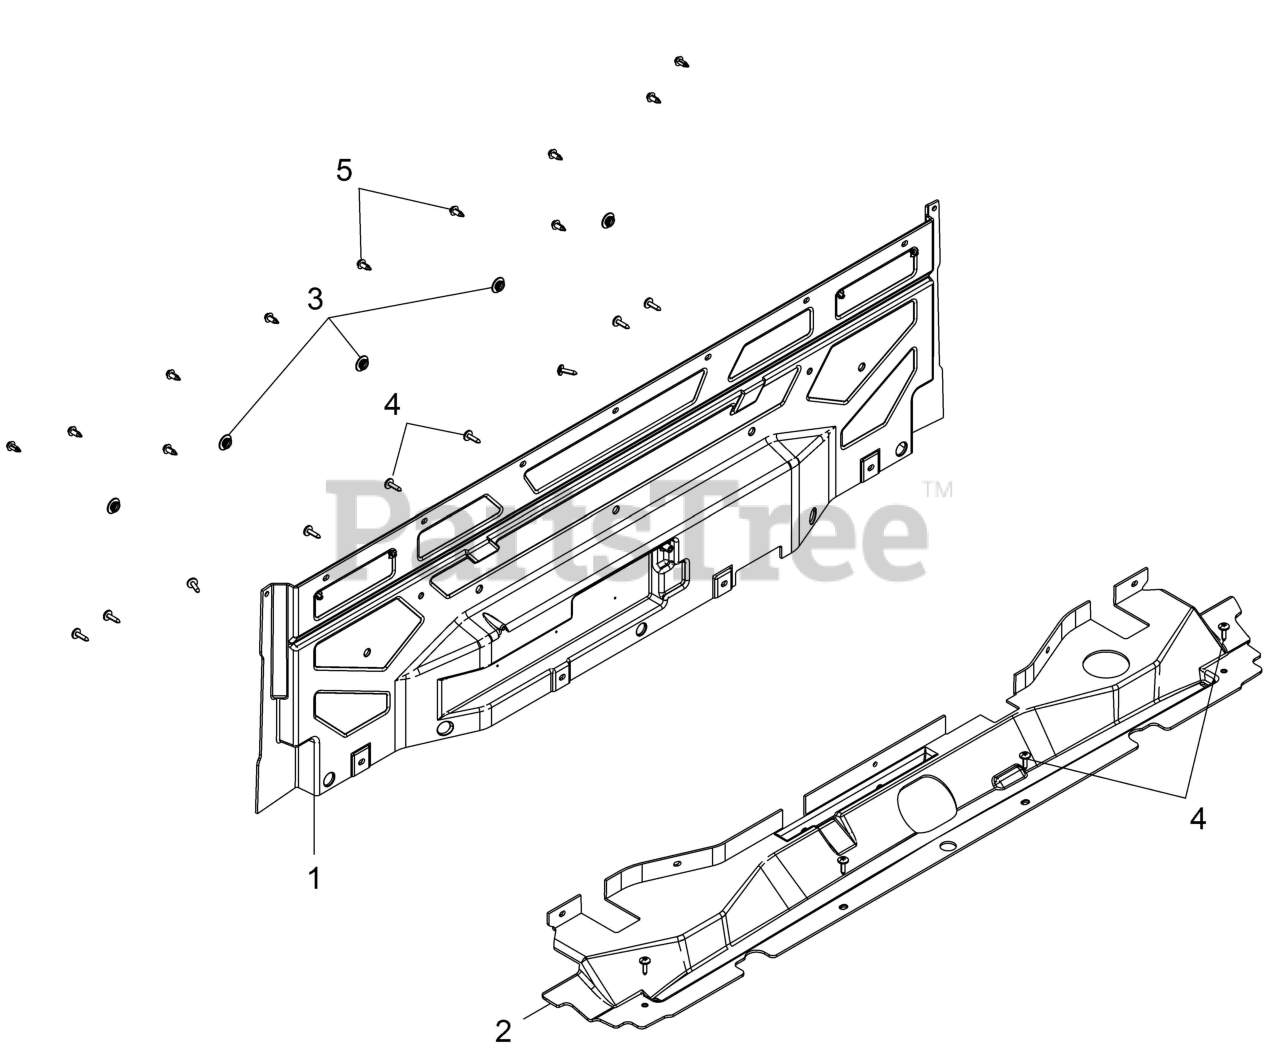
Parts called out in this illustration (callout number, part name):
1	PANEL, CLOSEOFF, REAR, BLK
2	PANEL-CLOSEOFF,LOWER,BLK
3	PLUG-COMPARTMENT
4	SCR-TXTH-M6X1.0X25 RIE
5	RIVET-TUFLOK,.315-.325X.787 (5
